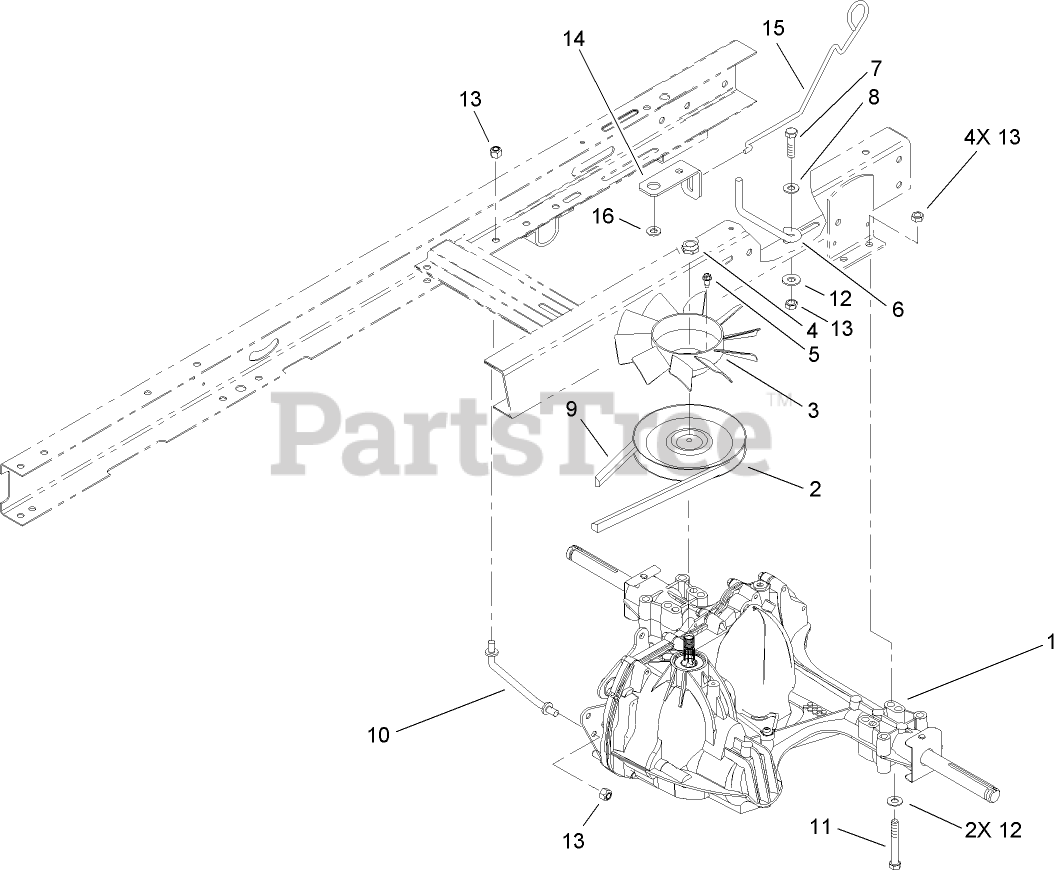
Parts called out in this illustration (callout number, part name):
1	TRANSAXLE ASM
2	PULLEY
4	NUT-LOCK, NI
5	SCREW-HWH
6	GUIDE-BELT
7	SCREW-HH
8	WASHER-PIVOT
9	V-BELT
10	STRAP-TORQUE
11	SCREW-HH
12	WASHER-PLAIN
13	NUT-LOCK, NI
14	BRACKET-BYPASS
15	ROD-BYPASS
16	WASHER-FLAT
